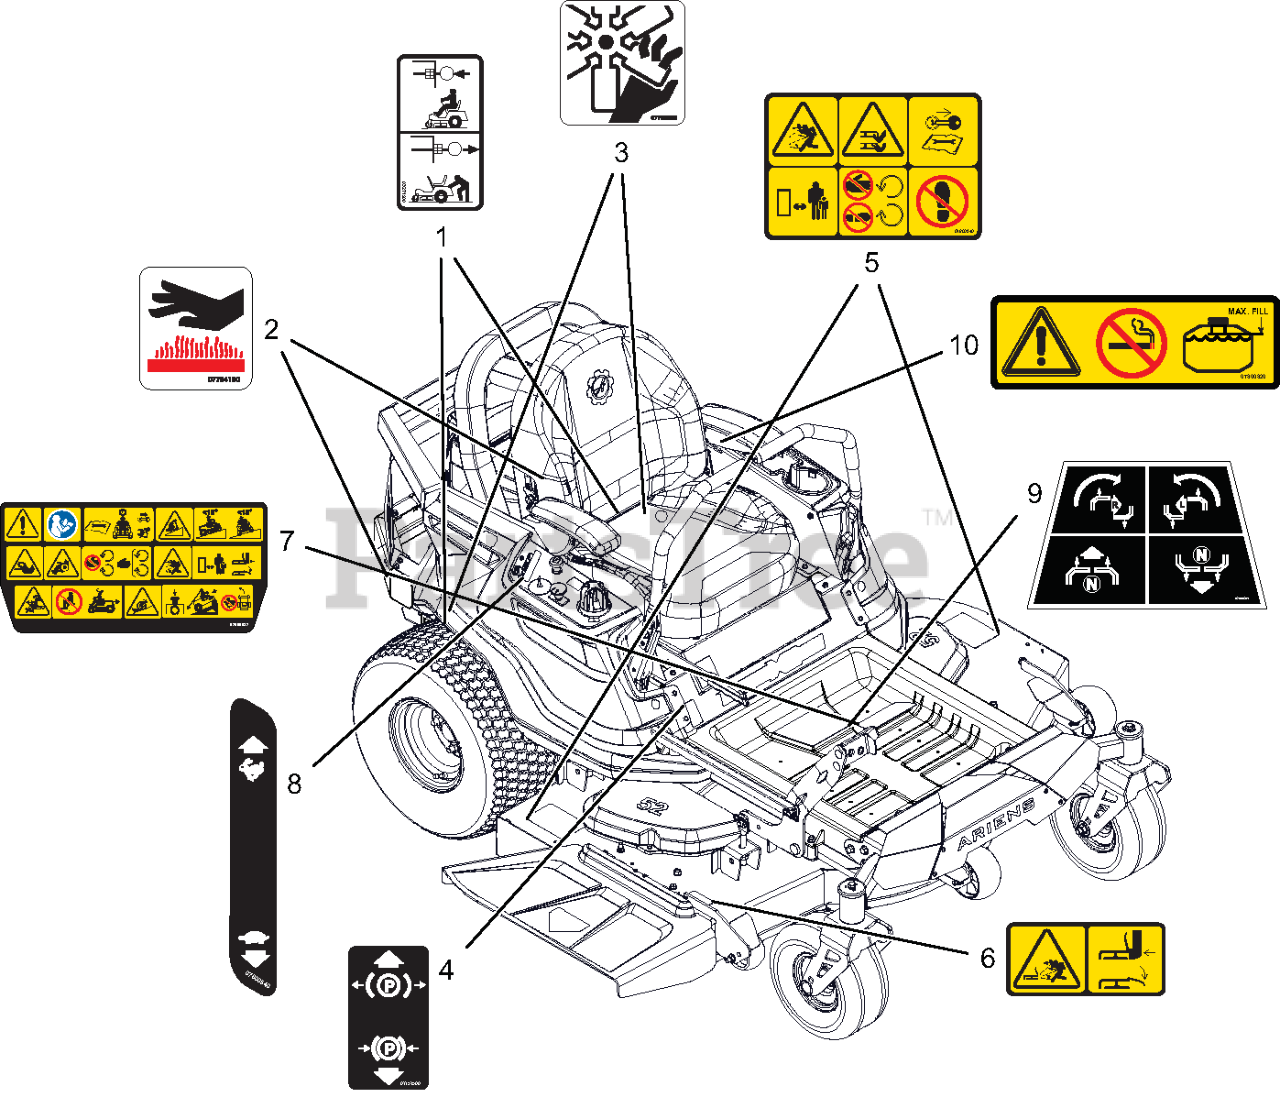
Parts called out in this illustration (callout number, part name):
1	DECAL, TRANSMISSION DISCONNECT
2	DECAL, HOT SURFACE
3	DECAL, DANGER - FAN
4	DECAL, PARKING BRAKE LEVER
5	DECAL, SAFETY - MOWER DECK
6	DECAL, SAFETY - DECK GUARDING
7	DECAL, MAIN SAFETY
8	DECAL, DASH DECAL
9	DECAL, STEERING
10	DECAL, FUEL WARNING
